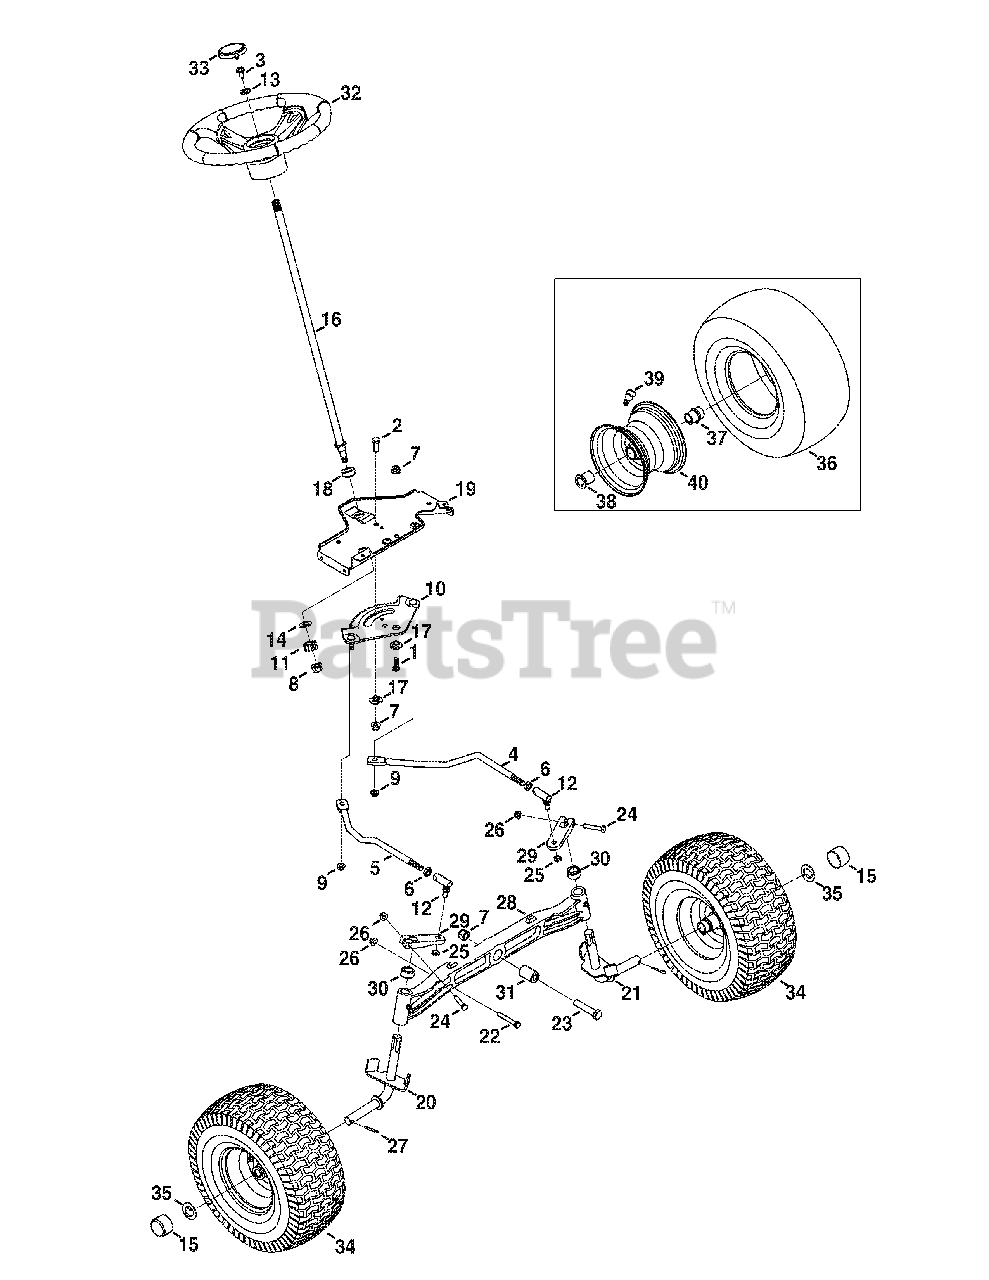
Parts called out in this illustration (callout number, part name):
1	Hex Head Screw, 3/8-16:1.00
2	Hex Head Screw, 3/8-16:1.00
3	Hex Head Screw, 5/16-18:1.00
4	LH Drag Link
5	RH Drag Link
6	Jam Nut, 7/16-20
7	Flangelock Nut, 3/8-16
8	Flangelock Nut, 7/16-20
9	Flangelock Nut, 5/16-18
10	Steering Gear
11	Steering Pinion Gear
12	Ball Joint, 7/16-20
13	Flat Washer, .406 X .875 X .105
14	Flat Washer, .51 X 1.12 X .06:HT
15	Bumper Cap
16	Steering Shaft, .625 OD X 24.25 LG
17	Shoulder Spacer, .385X 1.25 X .3025
18	Hex Flange Bearing 5/8 PM
19	Steering Support Bracket
19	Screw, .750 5/16-18
20	RH Axle Assembly
21	LH Axle Assembly
22	Hex Head Screw, 5/16-18:2.25
23	Hex Head Screw, 3/8-16:2.50
24	Hex Head Screw, 5/16-18:1.75
25	Hexlock Nut, 3/8-24
26	Flangelock Nut, 5/16-18
27	Cotter Pin, 5/32:1.25
28	Pivot Bar Axle
29	Steering Block
30	Spacer, .71 ID X .125 OD X .56LG
31	Spacer, .385 X 1.00 X 1.5075
32	Steering Wheel
33	Steering Wheel Cap
34	Wheel Assembly
35	Flat Washer, .781ID x 1.590OD
37	Flange Bearing, .760ID
38	Flange Bearing, .760 x 1.00 x 1.20LG
39	Tubeless Air Valve
40	Rim Assembly
